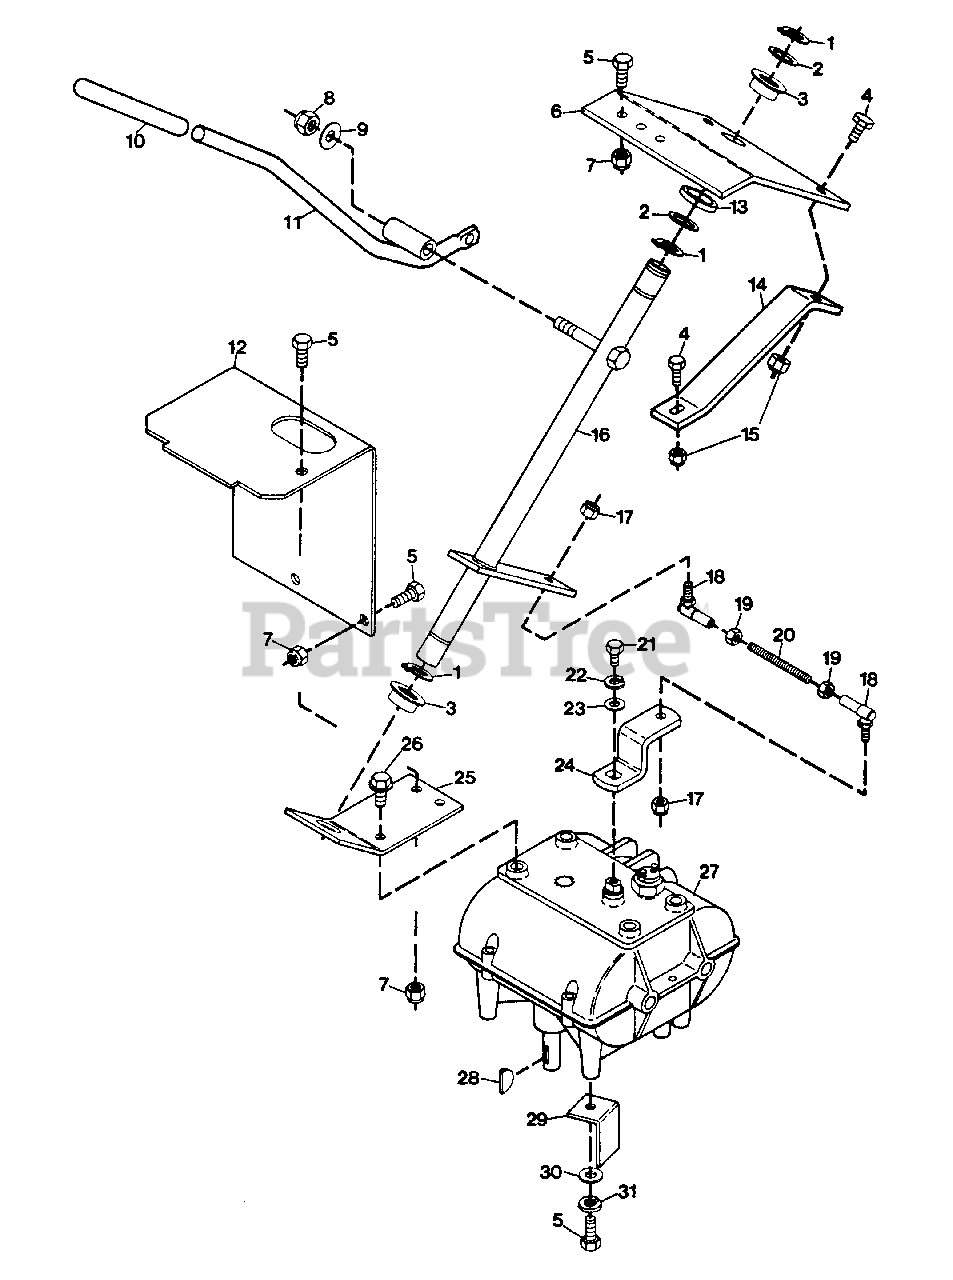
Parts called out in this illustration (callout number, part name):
1	RING, RETAINING
2	RACE, BEARING THRUST
3	BUSHING, NYLON .76X1X.6 FLANGE
4	BOLT, HEX 1/4-20X.75
5	BOLT, HEX 5/16-18X.75
6	PLATE, SHIFTER SUPPORT UPPER
7	NUT, LOCK 5/16-18
8	NUT, LOCK 3/8-16
9	WASHER, FLAT .406X.812X.065
10	GRIP, PTO LEVER
11	WELDMENT, SHIFT LEVER
12	GUARD, TRANSMISSION CHAIN
13	SPACER, SHIFTER SHAFT
14	BRACE, SHIFTER PLATE
15	NUT, LOCK 1/4-20
16	WELDMENT, SHIFTER SHAFT
17	NUT, LOCK 1/4-28
18	BALL JOINT, DISCONNECTING
19	NUT, HEX 1/4-28
20	ROD, TRANS. SHIFTER
21	BOLT, HEX 1/4-28X.50
22	WASHER, LOCK 1/4
23	WASHER, FLAT .281X.625X.065
24	ARM, TRANS. SHIFT
25	PLATE, SHIFT SUPPORT LOWER
26	BOLT, SELF-TAPPING 5/16-18X.62
27	TRANSMISSION, PRO LINE
28	KEY, WOODRUFF .187X.750 HARD
29	GUIDE, V-BELT
30	WASHER, FLAT .344X.688X.065
31	WASHER, LOCK 5/16 REG.
